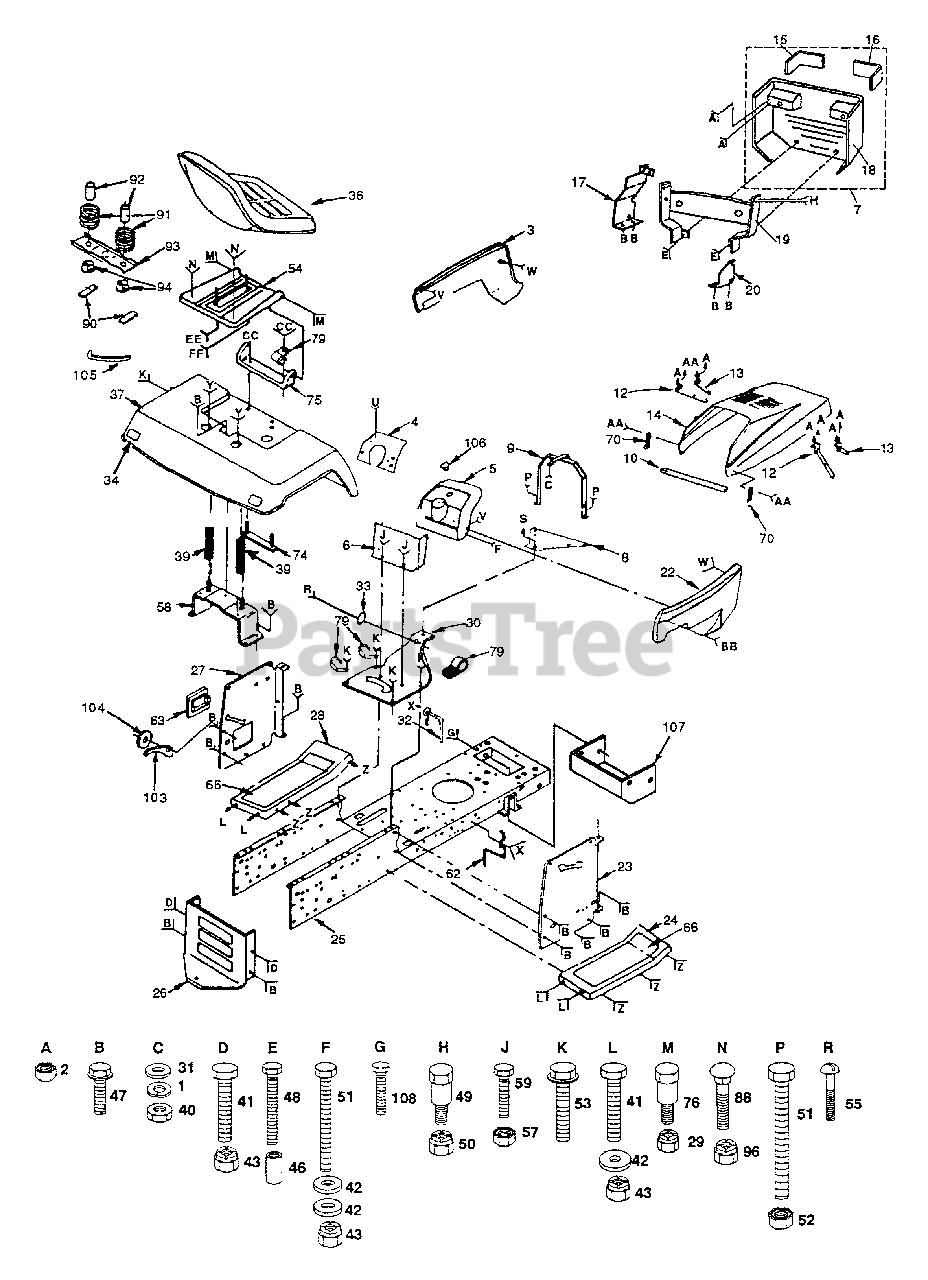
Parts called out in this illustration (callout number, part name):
1	Washer, Lock 1/4
2	Nut, Hex Keps 1/4-20
3	Panel, Side L.H.
4	Plate, Dashboard
5	Dashboard
6	Dash, Lower
7	Grill Assembly
8	Plate, Support, Battery
9	Support Assembly, Dash
10	Foam, Strip
12	Strap Assembly, Hinge, Rear
13	Strap Assembly, Hinge, Front
14	Hood
15	Lens, L.H.
16	Lens, R.H.
17	Bracket Assembly Frame Pivot L.H.
18	Grill
19	Support, Grill Assembly
20	Bracket Assembly Frame Pivot R.H.
22	Panel, Side, R.H.
23	Panel, Dash, R.H.
24	Footrest, R .H.
27	Panel, Dash, L.H.
28	Footrest, L.H.
29	Nut, Crownlock 5/16-18
30	Saddle
31	Washer 9/32 x 3/4 x 16 Ga.
32	Guide, Belt, Lower, Engine Pulley, L.H.
33	Bushing, Steering
34	Reflector, Taillight
36	Seat
39	Spring,Seat
40	Nut, Hex 1/4-20
41	Bolt, Hex 3/8-16 x 3/4
42	Washer 13/32 x 13/16 x 12 Ga.
43	Nut, Crownlock 3/8-16
47	Screw, Hex Washer Hd. Thd. Rolling 3/8-16 x 3/4 Type TT
48	Bolt, Hex Fin. 1/4-20 x 2-1/2
49	Bolt, Shoulder 1/4-20
50	Nut, Crownlock 1/4-20
51	Bolt, Hex 3/8-16 x 1-1/4
52	Nut, Keps 3/8-16
53	Screw, Hex Washer Hd. Thd. Forming 3/8-16 x 1/2 Type TT
55	Screw, Hex Head Self Tapping #10-16 x 1/2 Type B
57	Nut, Keps 5/16-18
58	Bracket Assembly, Fender
59	Screw, Truss Hd. 5/16-18 x 3/4
62	Guide, Belt, Lower, Engine, Pulley, R.H.
63	Cover, Access
66	Pad, Footrest
70	Latch, Hood
74	Strap Assembly, Fender
75	Bracket, Pivot, Seat
76	Bolt, Shoulder
79	Clip, Fuel Line
88	Bolt Carriage 1/4 - 20 x 1-1/4
90	Foam Strip
93	Bracket, Switch Mount
94	Snap Bushing
96	Nut, Hex Large Flange Lock
103	Pointer, Height Indicator
104	Washer, Nylon .44 x .75 x .032
105	Tie, Cable
106	Plug, Button
107	Shield, Heat
108	Screw, Tap Hex #10-24 x 1/2
